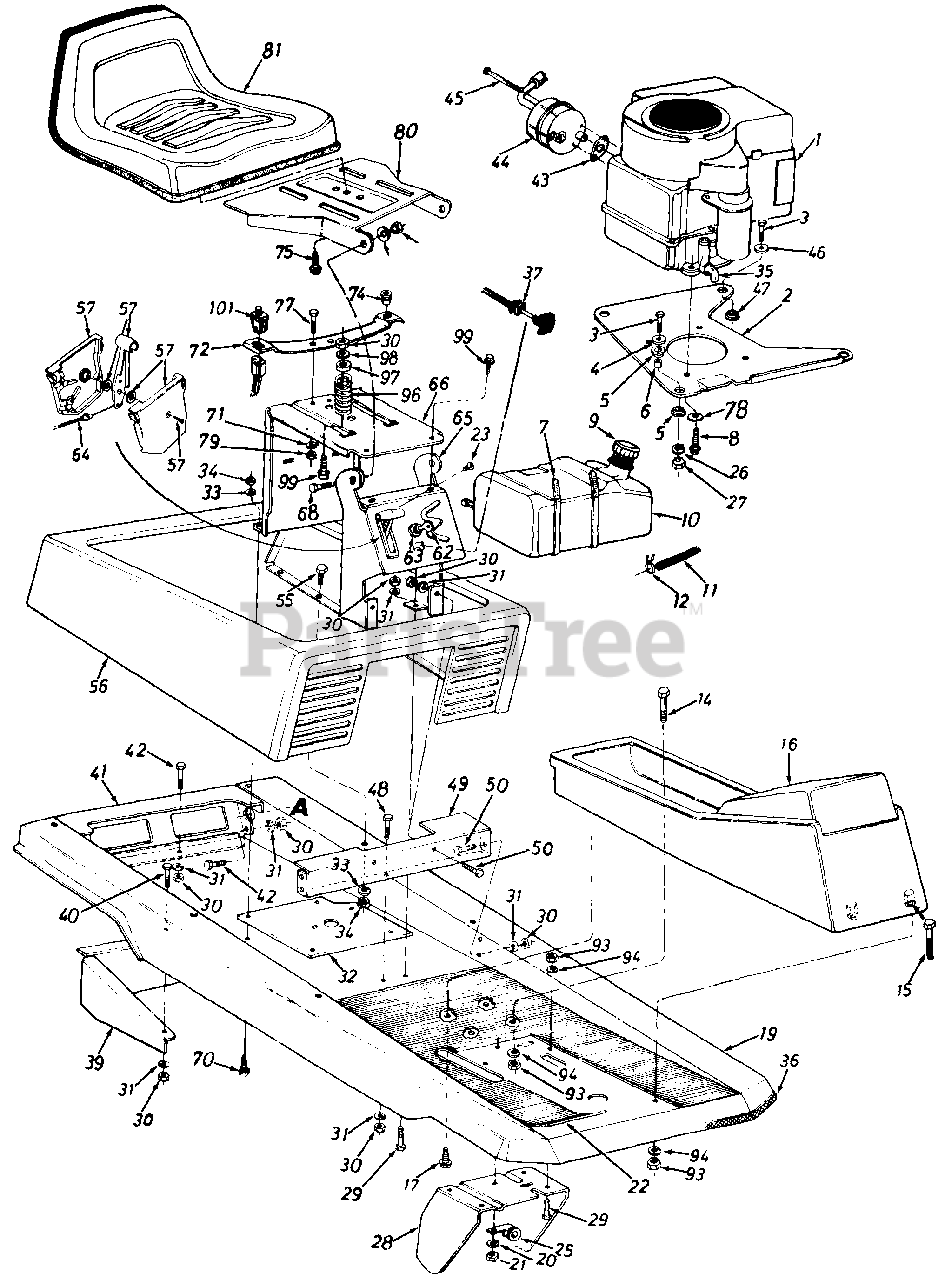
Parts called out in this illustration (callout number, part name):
1	Engine
4	Fl-Wash. .330" I.D. x 1.125" O.D.
5	Engine Mounting Grommet
6	Spacer .315" I.D. x .50" O.D. x .520" Lg.
7	Cable Tie 30.6" Lg.
8	Hex Wash. Hd. Self-Tap Scr. 3/8-16 x 1.25" Lg.
9	Gas Cap
10	Fuel Tank
11	Gas Line - 26 Inches
12	Hose Clamp - 1/2" O.D. Tube
14	Hex Bolt 5/16-18 x 1.75" Lg.
15	Hex Bolt 5/16-18 x 2.0" Lg.
16	Front Console
17	Plastite Scr. 5/16 x 1.25" Lg.
19	Main Frame
20	L-Wash. 5/16" I.D.
21	Hex Nut 5/16-18 Thd.
23	Truss Mach. AB-Tap Scr. #10 x .50" Lg.
26	L-Wash. 5/16" I.D.
27	Hex Nut 5/16-24 Thd.
28	Clutch-Brake Pedal Ass'y.
29	Hex Bolt 5/16-18 x .75" Lg
30	Hex Nut 5/16-18 Thd.
31	L-Wash. 5/16" I.D.
34	Hex Nut 1/4-20 Thd.
35	90° Elbow Male To Female
36	Trim Strip 18" Lg.
37	Choke Control
43	Exhaust Gasket
44	Muffler Ass'y.
45	Shld. Bolt
46	Fl-Wash. .33" I.D. x 1.25" O.D.
47	Flange Wash. .32" I.D. x .75" O.D.
48	Hex Bolt 5/16-18 x .75" Lg.
49	Seat Support & Frame Brkt.
50	Hex Bolt 5/16-18 x .75" Lg.
55	Hex Bolt 1/4-20 x .50" Lg.
62	Ignition Key
63	Ignition Switch
64	Throttle Control Wire 35" Lg.
70	Hex Tap Scr. 1/4-20 x 1.0" Lg.
71	L-Wash. 5/16" I.D.
75	Hex Wash. Hd. Tap Scr. 3/8-16 x 3/4" Lg.
77	Hex Bolt 5/16-18 x .75" Lg.
78	Bell-Wash. .345" I.D. x .88" O.D.
79	Hex Cent. L-Nut 5/16-18 Thd.
80	Seat Pivot Bracket
81	Seat Ass'y.
93	Hex Nut 5/16-18 Thd.
94	L-Wash. 5/16" I.D.
96	Compression Spring 2.61" Lg.
98	Fl-Wash. .344" I.D. x .875"
99	Hex Bolt 5/16-18 x 1" Lg. (Gr. 5)
